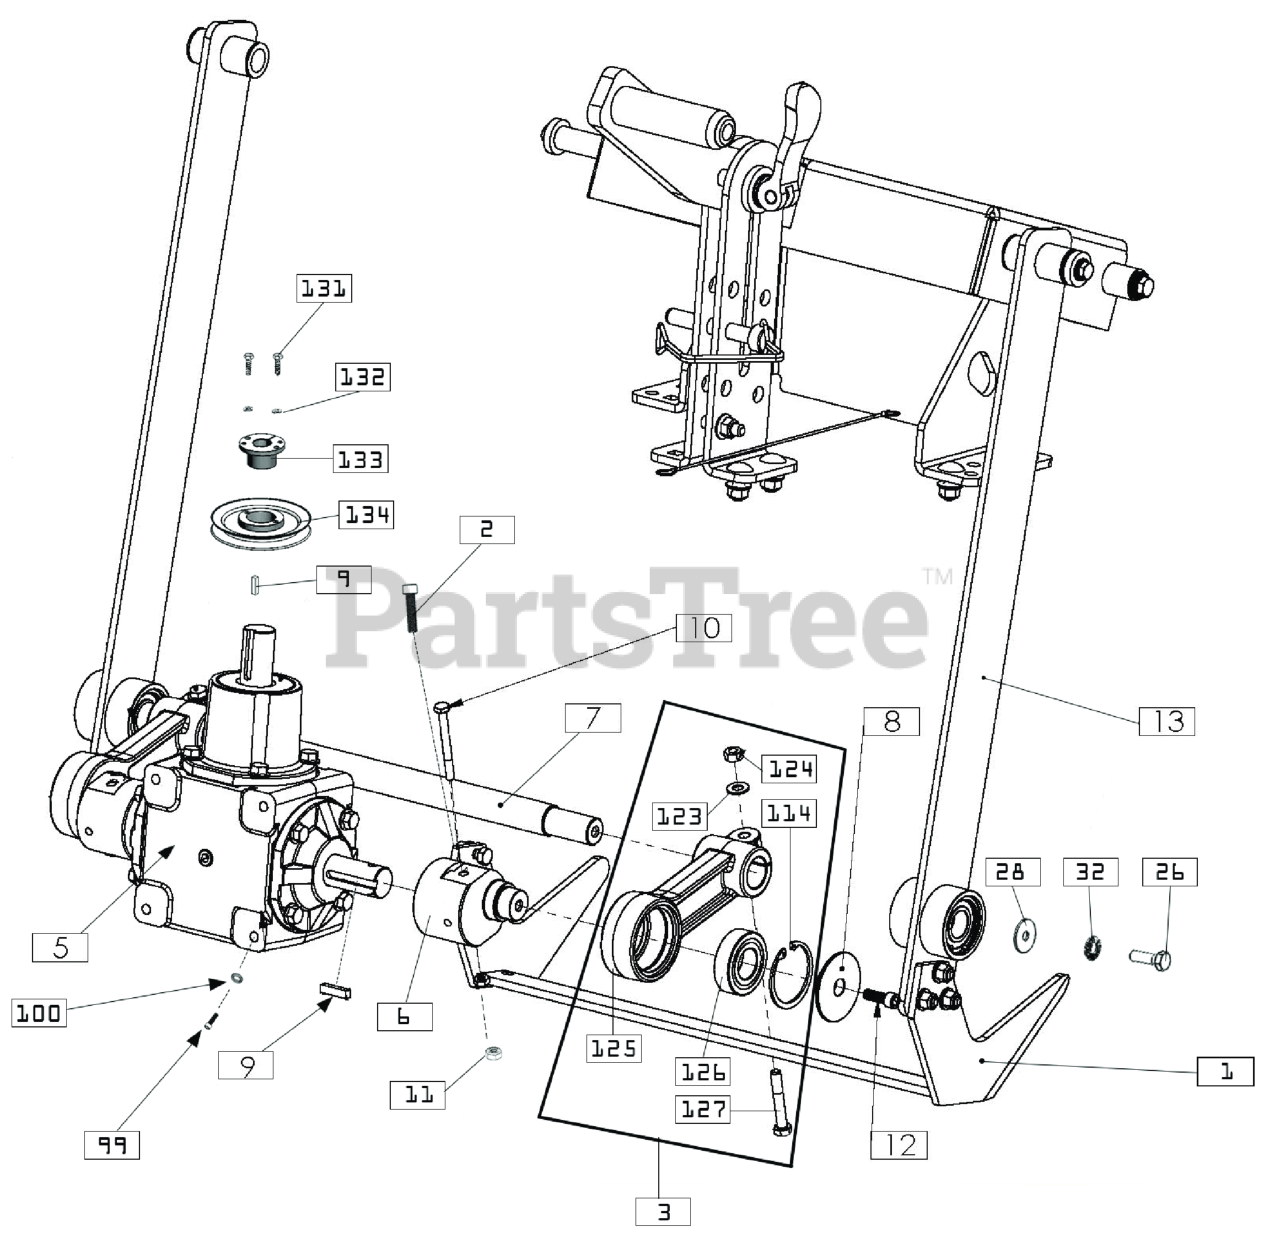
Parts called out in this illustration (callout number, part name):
1	KIT BLADE 18" INCLUDES HARDWARE
2	SHCS 5/16"-18 X 1.25 BLK OX
3	ROD, CONNECTING ASSY SC181H
5	GEARBOX, SPIRAL BEVEL 2:1 CURTIS
5	SC181 GEARBOX SEAL KIT
6	ECCENTRIC, BLADE DRIVE SC181H
7	BAR, PUSH
8	WASHER, CONNECTING ROD
9	KEY SQUARE 1/4" X 1"
10	SCREWCAP 1/4"-20X2 1/2" ZP
11	NUT LOCK, 1/4-20 LT WT TH ZP
12	SCR-CAP, SH .3125"-24 X 0.875" G8 ZP
13	ARM, BLADE SC181H ASSY
26	SCREWCAP 5/16"-18 X 1" HCS ZP
28	WASHER 1.125 OD X 0.344 ID X .25 THK ZP
32	WASHER, BELLEVILLE CONTACT .323X.717X.05
99	SCR-CAP, SH .375" - 16 X 1.250" G8 ZP
100	WSHR-NORD LOCK 0.406" X 0.654" ZP
114	RING, RETAINING DHO-47
123	WASHER 5/16" SAE Z/P
124	NUT 5/16"-24 FIN HEX Z/P
125	CONNECTING ROD, MACHINED SC181
126	BEARING, 6205 25MM BORE ARMORED SEALS
127	SCREWCAP 5/16-24 X 2" GR.8
131	SCREWCAP 1/4"-20 X 1" HCS ZP
132	WASHER LOCK 1/4" S/T MED
133	BUSHING, TAPERED HUB Ø1.000" BORE
134	PULLEY, BLADE DRIVE
